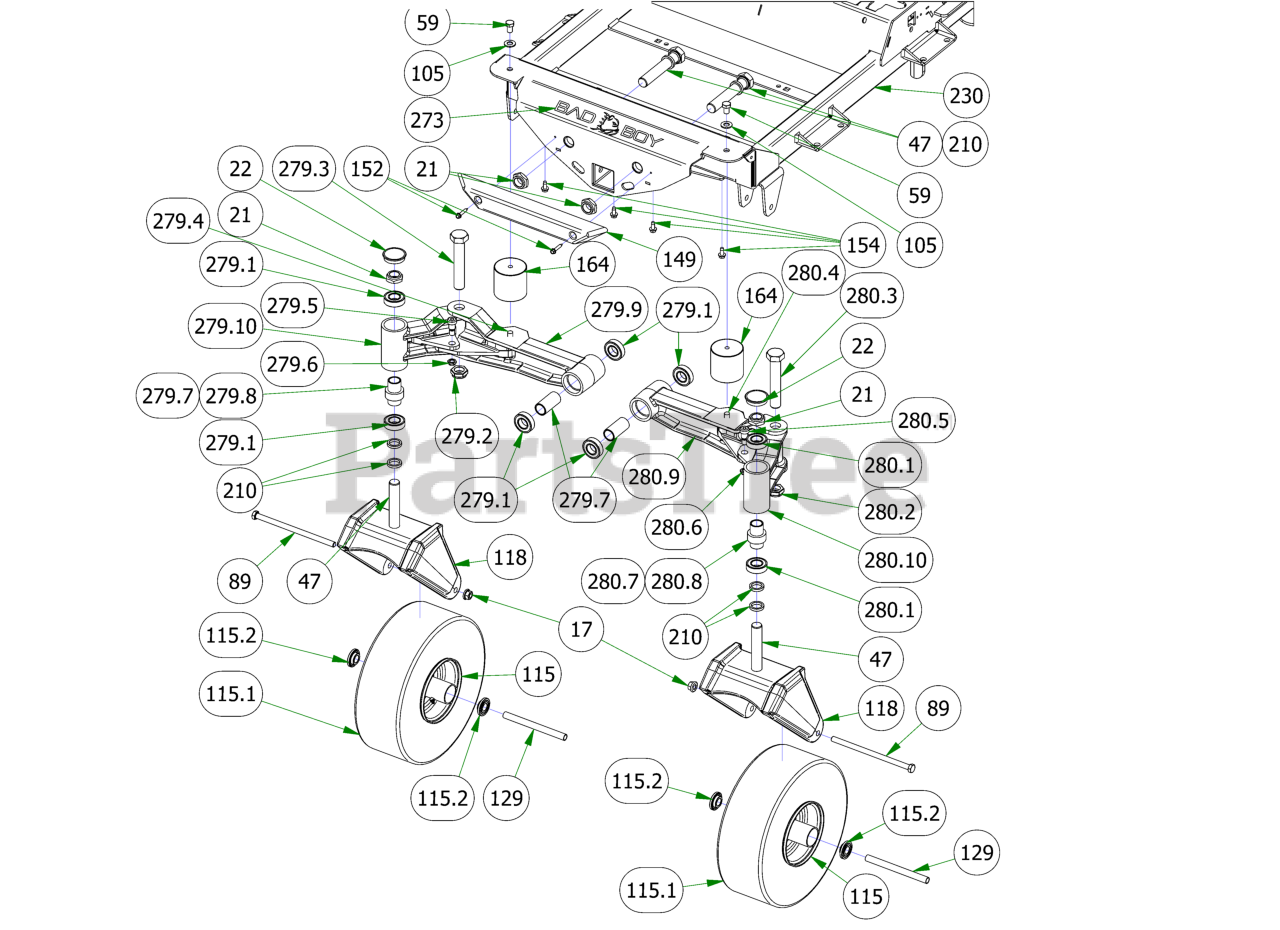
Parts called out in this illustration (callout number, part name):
17	1/2-13 NYLON INSERT FLANGE LOCKNUT ZINC
21	1"-14 NYLON INSERT JAM LOCKNUT ZINC
22	2017 Bearing Cover
47	1"-14 X 5-1/2 HEX CAP SCREW (GR.8) ZINC YELLOW
59	1/2-13 X 3/4 HEX CAP SCREW (GR.5) ZINC
89	1/2-13 X 9 HEX CAP SCREW (GR.5) ZINC
105	1/2 SAE FLAT WASHER (1-1/16" OD) GR.8 ZINC YELLOW
115	2019 15x6.00-6 Non Pneumatic Black Front Assembly
115.1	15x6-6 Tire Only
115.2	1-3/4" Bearing-Large Bore Front Rim
118	2020 R Series Cast Front Fork
129	Front Wheel Spanner
149	2017 XP BUMPER
152	1/4-14 X 1-1/2 HEX WASHER UNSLOT TEK/3 ZINC
154	5/16-18 X 3/4 HEX WASHER SLOT (F) TCS ZINC
164	Vibration Mount-Blue Dot
210	1.02 ID X 1.38 OD X .250 THK SPACER ZINC
230	2019 Renegade Gas Frame - Powdercoated
273	Flying Bulldog Front Bumper Decal
276	Independetly Articulating Front Suspension Arms Patent Decal
279	2022 61/72 Rogue/Renegade Front Suspension Asy RH
279.1	1641 BEARING W/2 CONTACT RUBBER SEALS
279.2	1" Fine Thread 1/2 Nylock Nut
279.3	1"-14 X 5-1/2 HEX CAP SCREW (GR.8) ZINC YELLOW
279.4	1/2-13 x 1" Stud
279.5	5/8 X 5/8 SOCKET SHOULDER BOLT ZINC YELLOW
279.6	1/2-13 NYLON INSERT JAM LOCKNUT ZINC
279.7	2016 Front Bearing Spacer
279.8	Rubber Stabilizer (Front Forks) [R series]
279.9	61" & 72" Rogue Front Suspension Arm Inner RH
279.10	61" & 72" Rogue Front Suspension Arm Outer RH
280	2022 61/72 Rogue/Renegade Front Suspension Asy LH
280.1	1641 BEARING W/2 CONTACT RUBBER SEALS
280.2	1" Fine Thread 1/2 Nylock Nut
280.3	1"-14 X 5-1/2 HEX CAP SCREW (GR.8) ZINC YELLOW
280.4	1/2-13 x 1" Stud
280.5	5/8 X 5/8 SOCKET SHOULDER BOLT ZINC YELLOW
280.6	1/2-13 NYLON INSERT JAM LOCKNUT ZINC
280.7	2016 Front Bearing Spacer
280.8	Rubber Stabilizer (Front Forks) [R series]
280.9	61" & 72" Rogue Front Suspension Arm Inner LH
280.10	61" & 72" Rogue Front Suspension Arm Outer RH
